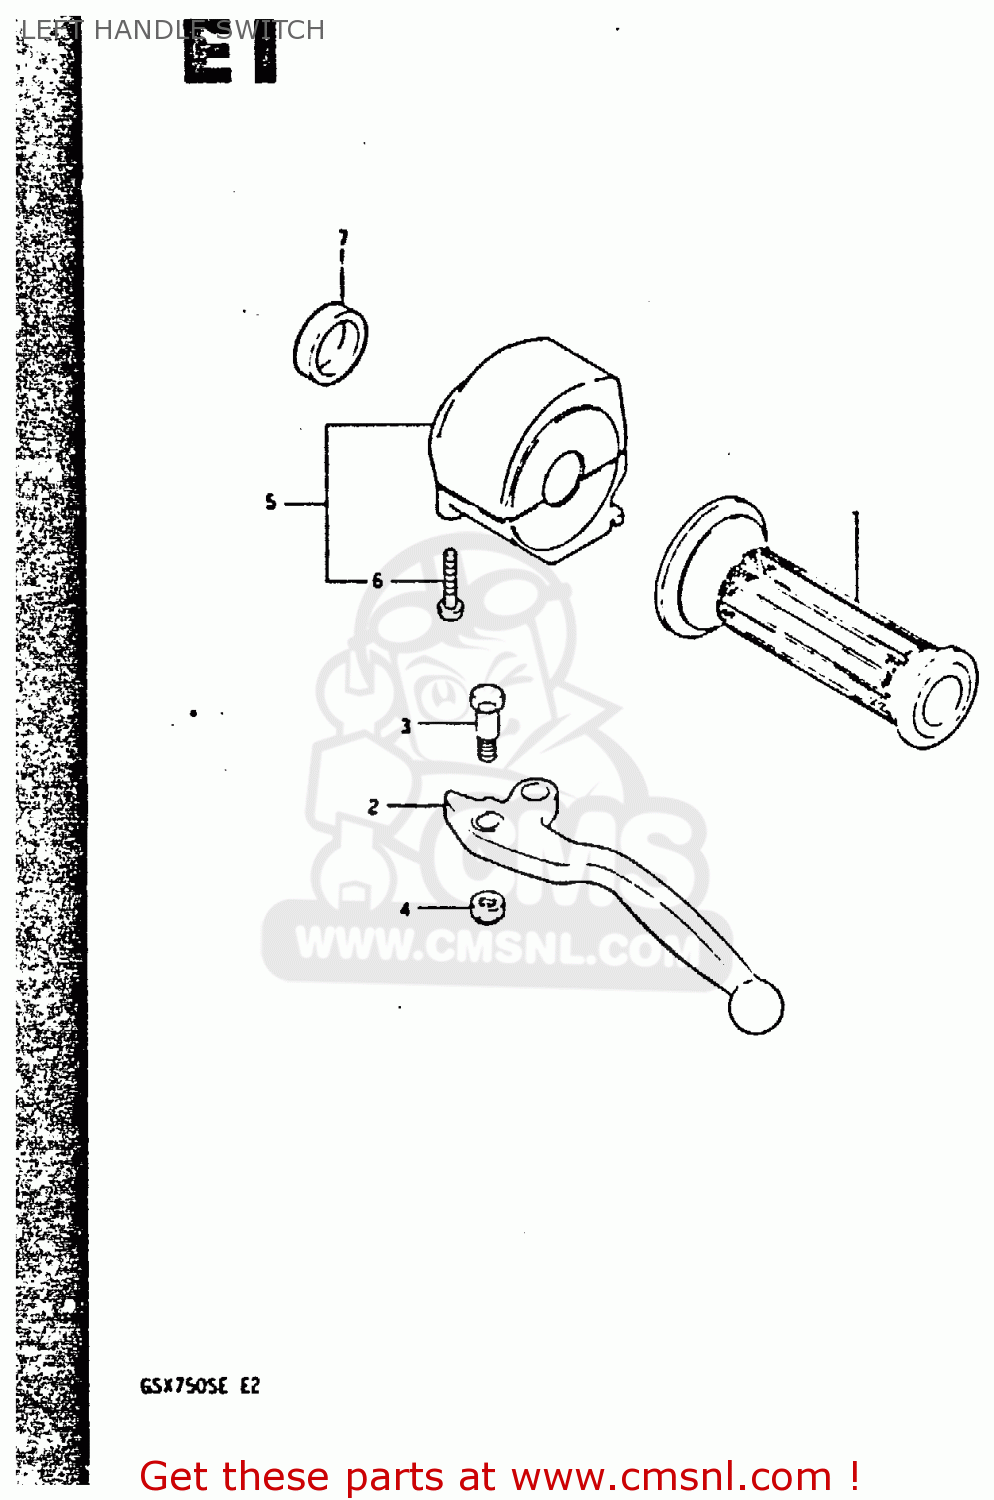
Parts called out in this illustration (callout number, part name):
1	GRIP,L
2	LEVER,CLUTCH (BLACK)
3	BOLT,LEVER
4	NUT
5	SWITCH ASSY, HANDLE LH
6	SCREW
7	SPACER
